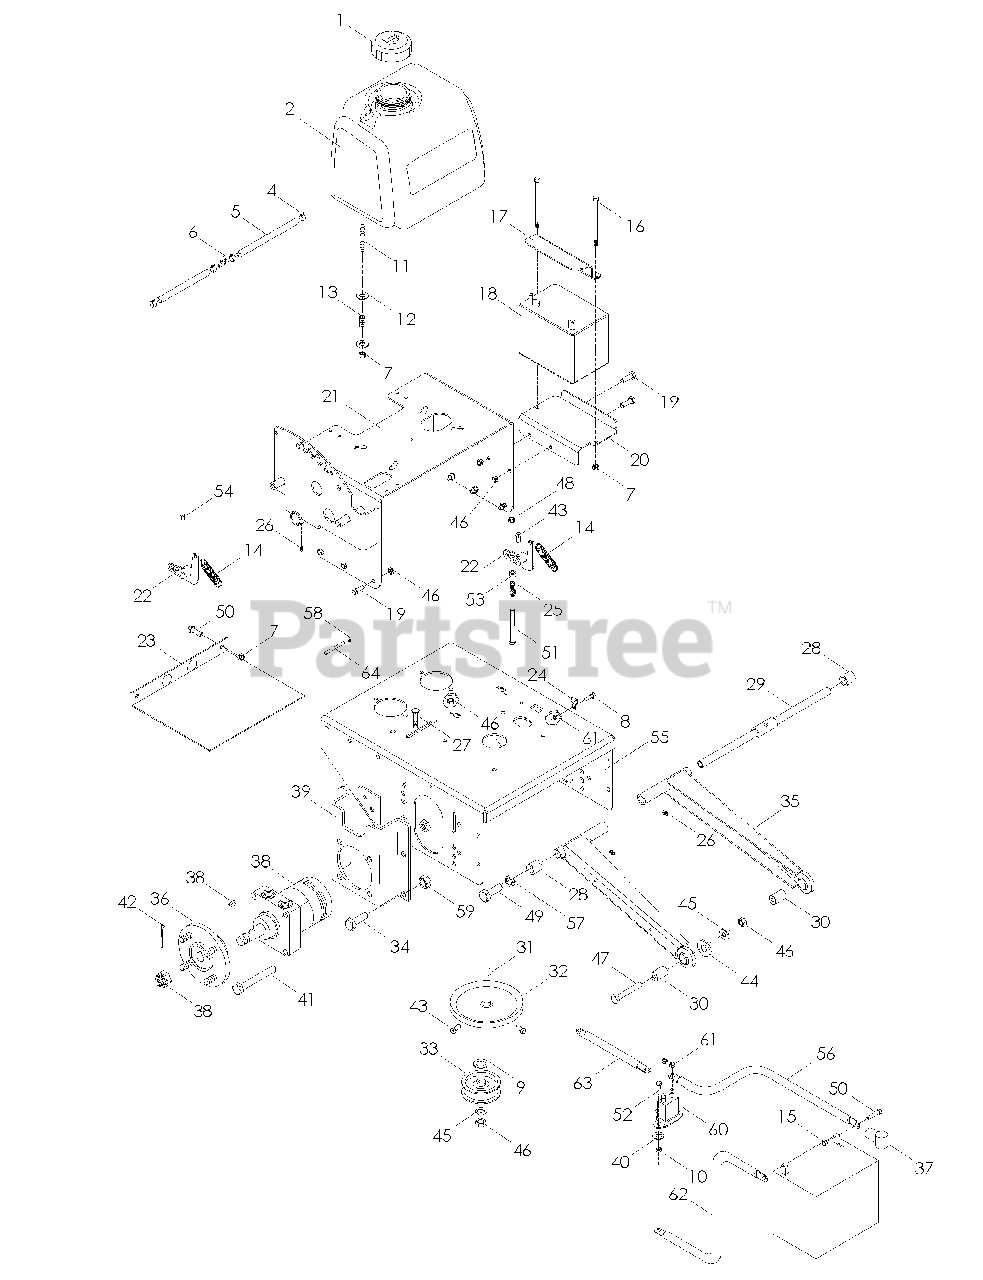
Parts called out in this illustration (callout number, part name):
1	CAP, FUEL
2	TANK, FUEL
3	NUT 1/4-20 THIN NYLOC
4	CLAMP, HOSE
6	VALVE, FUEL
7	NUT 5/16-18 HEX NYLOC
8	HCS 1/4-20 x 3/4
9	WASHER 3/8
10	NUT 1/4-20 CNTRLK
12	WASHER 5/16 STD FLT
14	SPRING, PUMP
15	NUT 5/16-18 HEX CTRLK
16	HCS 5/16-18 x 7
17	STRAP, BATTERY
18	BATTERY, DRY
19	HCS 3/8-16 x 3/4
20	TRAY, BATTERY
21	SUPPORT, TANK
23	SHIELD, BELT
26	ZERK
27	RHSNB 3/8-16 x 2
29	SHAFT, STRUT
30	SPACER, FRONT
31	KEY, METRIC
33	PULLEY, IDLER
34	HFCS 1/2-13 x 1 1/4
38	MTR, HYDRO W/KEY, NUT
39	MOUNT, MOTOR
40	LOCKWASHER IT 1/4
41	HCS 1/2-13 x 2 3/4
42	COTTER PIN
43	SCREW 5/16-18 x 5/8 SET
44	WASHER 1/2 STD FLT
45	WASHER 3/8 FLAT
46	NUT 3/8-16 HEX CNTRLK
47	HCS 3/8-16 x 2 1/4
48	NUT 3/8-16 HEX NYLOC
49	HCS 1/2 x 1
50	HCS 5/16-18 x 3/4
51	HCS 3/8-16 x 2 3/4
52	HCS 1/4-20 x 5/8
54	SCREW 5/16-18 x 5/8
55	DECK W/DECALS, REAR
56	CABLE, POSITIVE
57	LOCKWASHER 1/2
59	NUT 1/2-13 HEX NYLOC
61	NUT 1/4-20 HEX NYLOC
62	CABLE, NEGATIVE
63	CABLE, POSITIVE
64	PIN, CLEVIS
